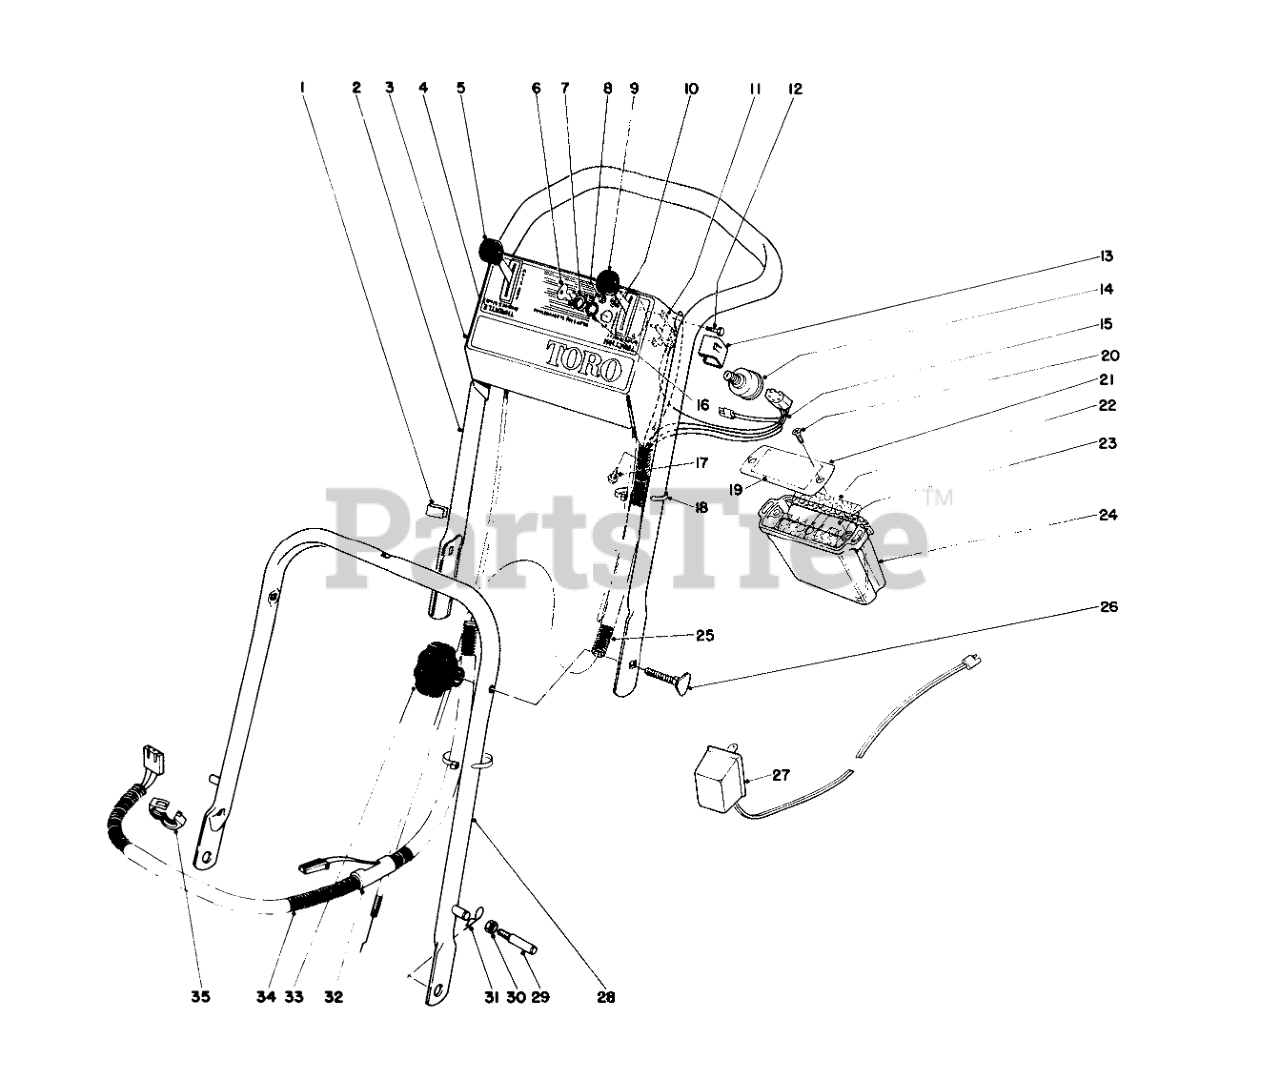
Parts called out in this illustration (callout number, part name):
2	UPPER HANDLE
3	Control Plate
4	Decal Control Plate
5	Control Throttle
6	Key
7	NUT-HH
8	NUT-HEX
9	Traction Control
10	WASHER-FLAT
11	CONTROL SWITCH
12	SCREW-HH
13	Cover Switch
14	SWITCH-STARTER
15	Wire Harness
16	WASHER-TOOTH, INTERNAL
17	Screw
18	TIE-CABLE
19	Decal Battery
21	Cover
22	Spacer
23	Battery Pack Assembly (Incl. Ref. #19-22 & 24)
24	Container Pack
25	Cover Wiring Harnes Upper
26	SCREW-HANDLE
27	Charger
28	Lower Handle
29	HANDLE PIN
30	Nut
31	PIN-COTTER, HAIR
32	Breakout Fitting
34	Cover Wiring Harness Lower
35	RING FITTING
